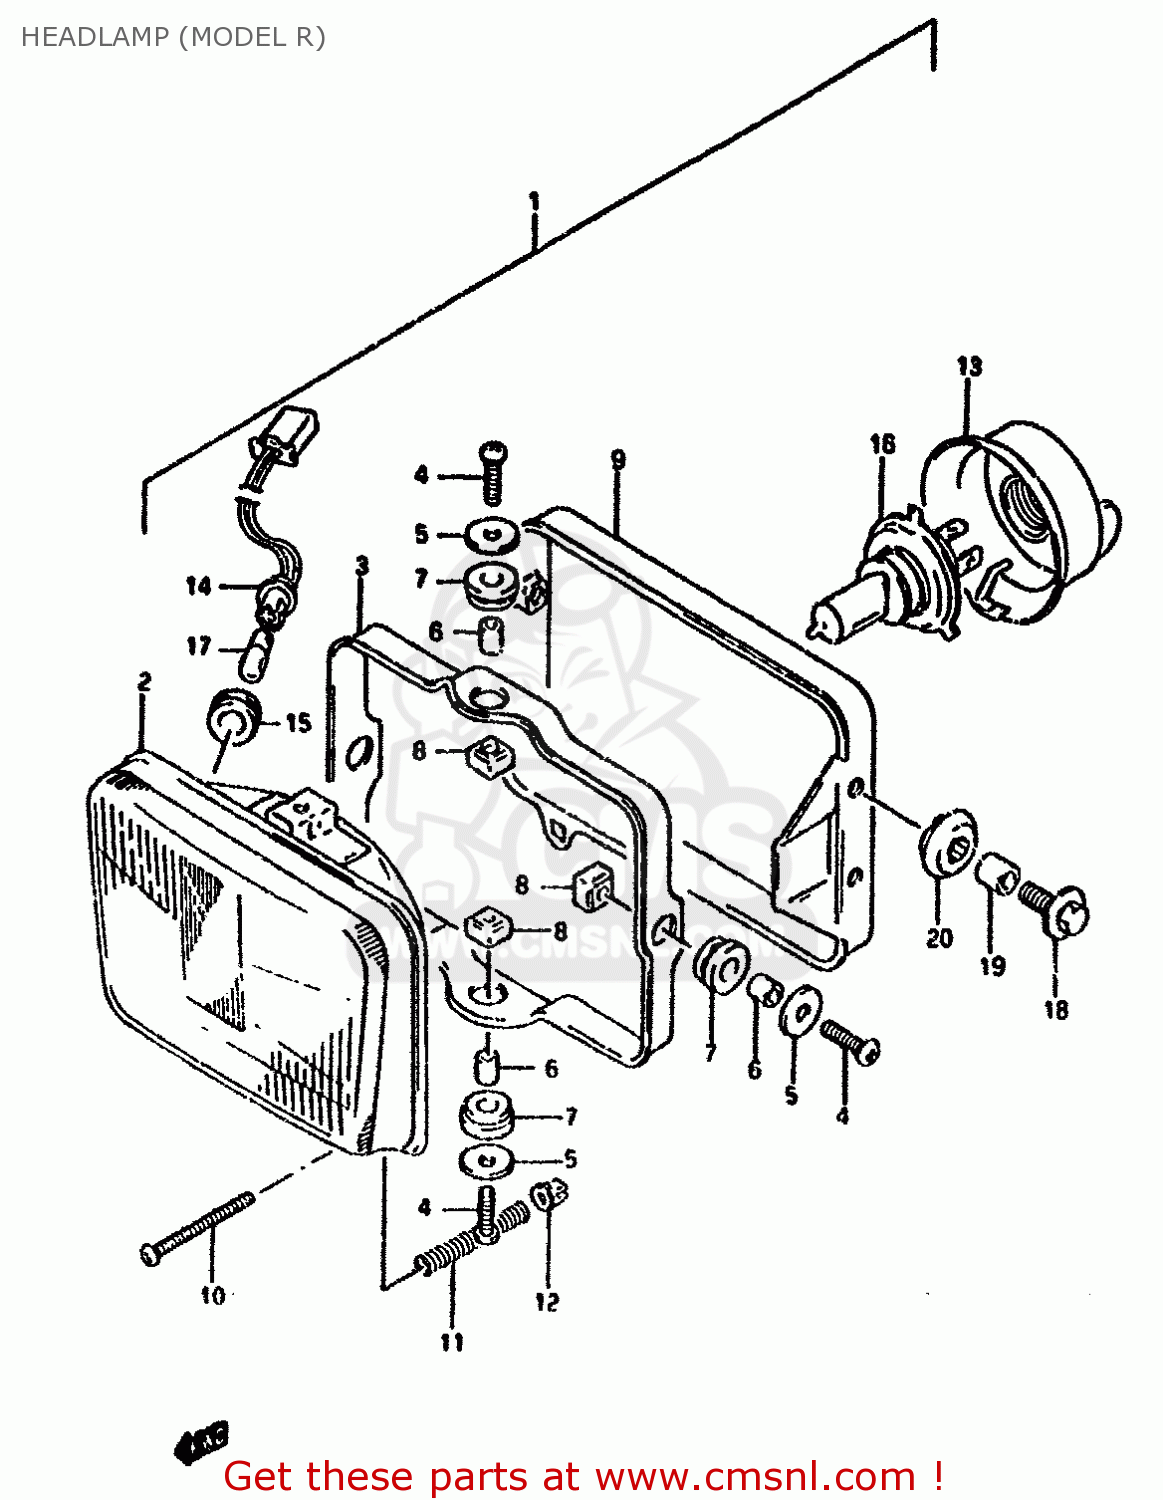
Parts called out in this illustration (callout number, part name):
1	HEADLAMP ASSY
2	UNIT ASSY
3	RING,MOUNTING
4	SCREW,HEADLAMP ADJUST
5	WASHER
6	SPACER
7	CUSHION
8	NUT
9	HOUSING
10	SCREW,HEADLAMP ADJUST
11	SPRING,ADJUSTING
12	NUT,ADJUSTING
13	COVER,SOCKET
14	CORD,POSITION
15	JOINT,RUBBER
16	BULB(12V4W)
17	BULB(12V60/55W,H4)
18	BOLT 6X20
19	SPACER (6.8X10X10)
20	CUSHION
